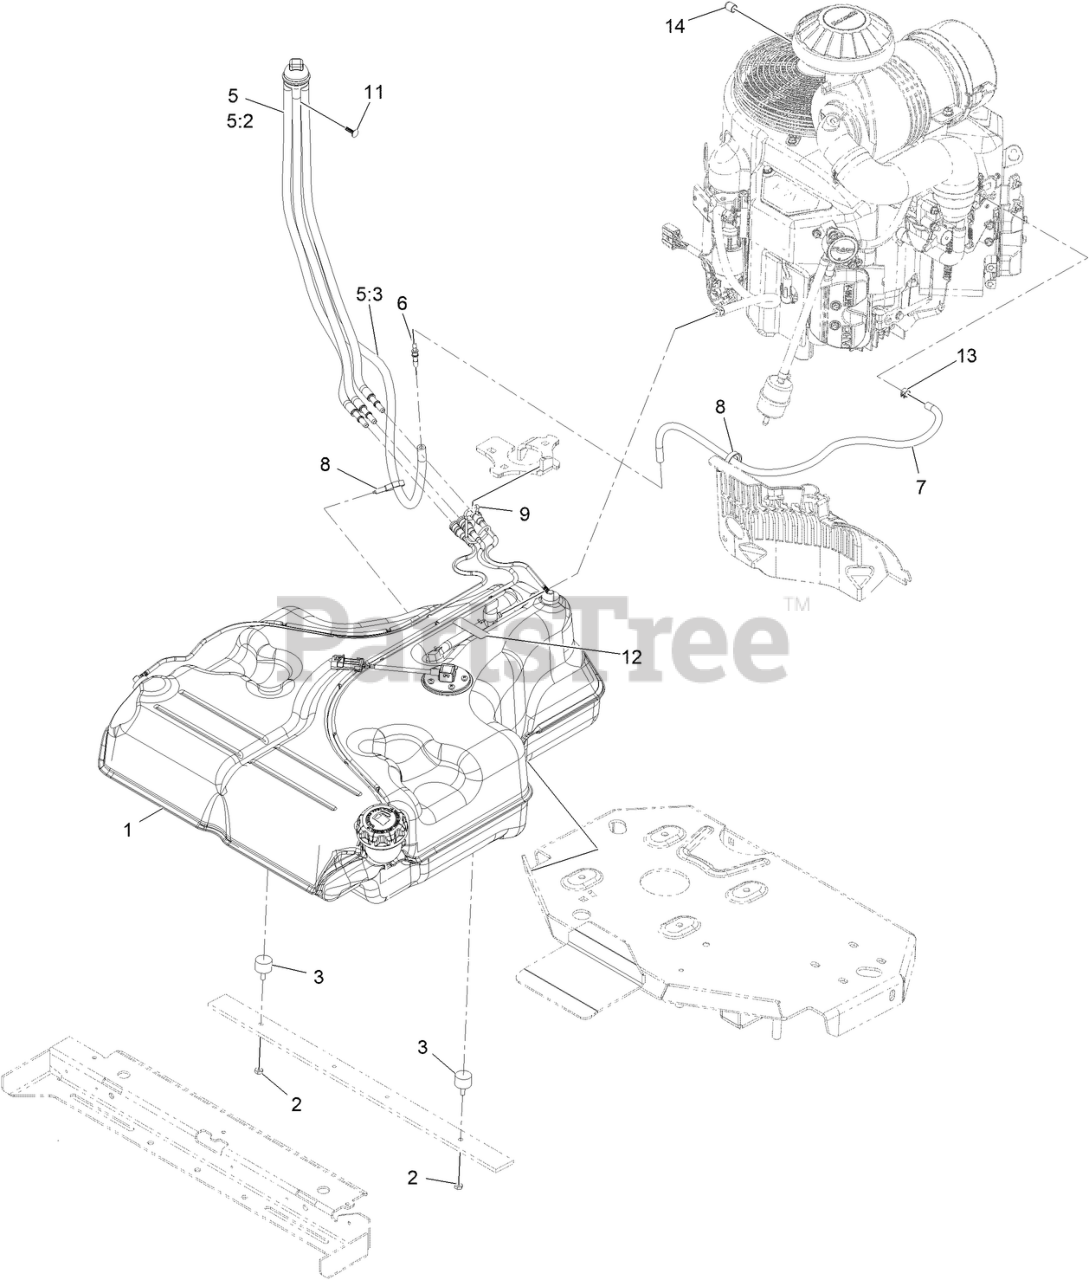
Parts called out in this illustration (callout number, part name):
1	FUEL TANK ASM
2	NUT-JAM
5	FUEL MANIFOLD VENT ASM
5:2	HOSE-FUEL
5:3	HOSE-FUEL
6	BARB-FUEL
7	Hose-Fuel
8	CLAMP-HOSE
9	RETAINER-LINE, VAPOR
11	PLUG-PLASTIC
12	DECAL-STRIP BLACK
13	CLAMP-HOSE
14	PLUG-PORT
